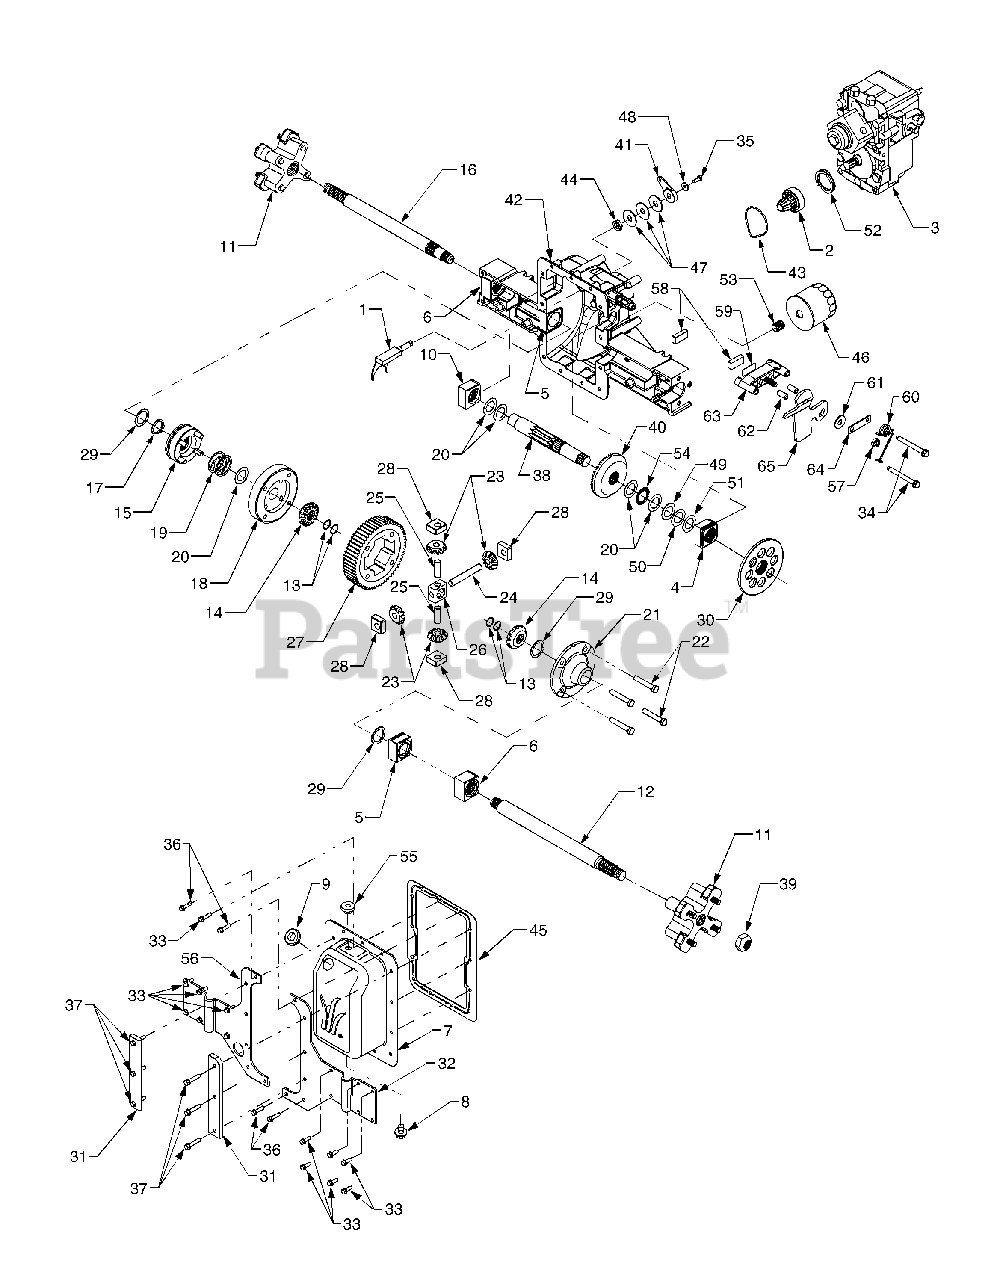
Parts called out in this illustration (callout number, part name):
1	Shaft, Differential Actuator
2	Gear Assembly, Pinion 13T
3	Hydrostatic Transmission Assy. Kit
4	Bearing Block Assembly, Needle
5	Bearing Block Assembly
6	Bearing Block Assembly
7	Cover Assembly, Rear
8	Plug, Drain, M14 x 1.5 x .827
9	Grommet, Rubber
10	Bearing Block Assembly
11	Hub Assembly, Wheel
12	Axle Shaft, 15.08 Long - RH
13	Retaining Ring
14	Gear, Spur, 14T
15	Collar Assembly, Diff. Lock
16	Axle Shaft, 15.08 Long - LH
17	Retaining Ring
18	Housing, Diff Lock
19	Spring, Compression
20	Washer, Thrust, 1.007 x 1.542 x .03
21	Housing, Diff. Cover
22	Hex Cap Screw, 3/8-24 x 2.25 GR8
23	Gear, Differential 10T
24	Shaft, Cross, .5 x 3.485
25	Shaft, Cross, Special
26	Differential Pinion Block
27	Gear, Spur 60T
28	Block, Thrust Miter
29	Washer, Flat, 1.187 x 1.56 x .062
30	Disc, Brake
31	Block, Transmission Cover
32	Plate, Trans Support RH
33	Screw, Hex Wash Hd. Tapp 1/4-20 x .75
34	Screw, Hex Wash Hd. Tapp 1/4-20 x 2.375
35	Hex Cap Screw, 1/4-20 x .62 GR5
36	Screw, Hex Wash Hd. Tapp 1/4-20 x 1.0
37	Screw, Hex Wash Hd. Tapp 1/4-20 x 1.25
38	Shaft, Output 9T
39	Nut, Lock, 7/8-14
40	Gear, Bevel 54T
41	Arm, Diff. Lock Actuator
42	Housing, Differential w/Diff. Lock
43	O-Ring, 2.75 x .103
44	Seal, Oil
45	Gasket
46	Filter, Oil
47	Washer, Flat, .51 x 1.5 x .07
48	Washer, Belleville, .265 x .75 x .062
49	Washer, Flat Shim, 1.0 x 1.56 x .010
50	Washer, Flat Shim, 1.0 x 1.56 x .020
51	Washer, Flat Shim, 1.0 x 1.56 x .015
52	Washer, Spring
53	Fitting, Filter Nipple
54	Bearing, Needle Thrust
56	Plate, Trans Support LH
57	Nut, Hex Insert Lock, 5/16-24
58	Pad, Brake
59	Plate, Puck
60	Spring, Torsion
61	Washer, Flat, .343 x .88 x .062
62	Pin, Brake Actuator
63	Yoke, Brake
64	Bracket, Brake Anti-Rotation
65	Arm, Brake Actuator
